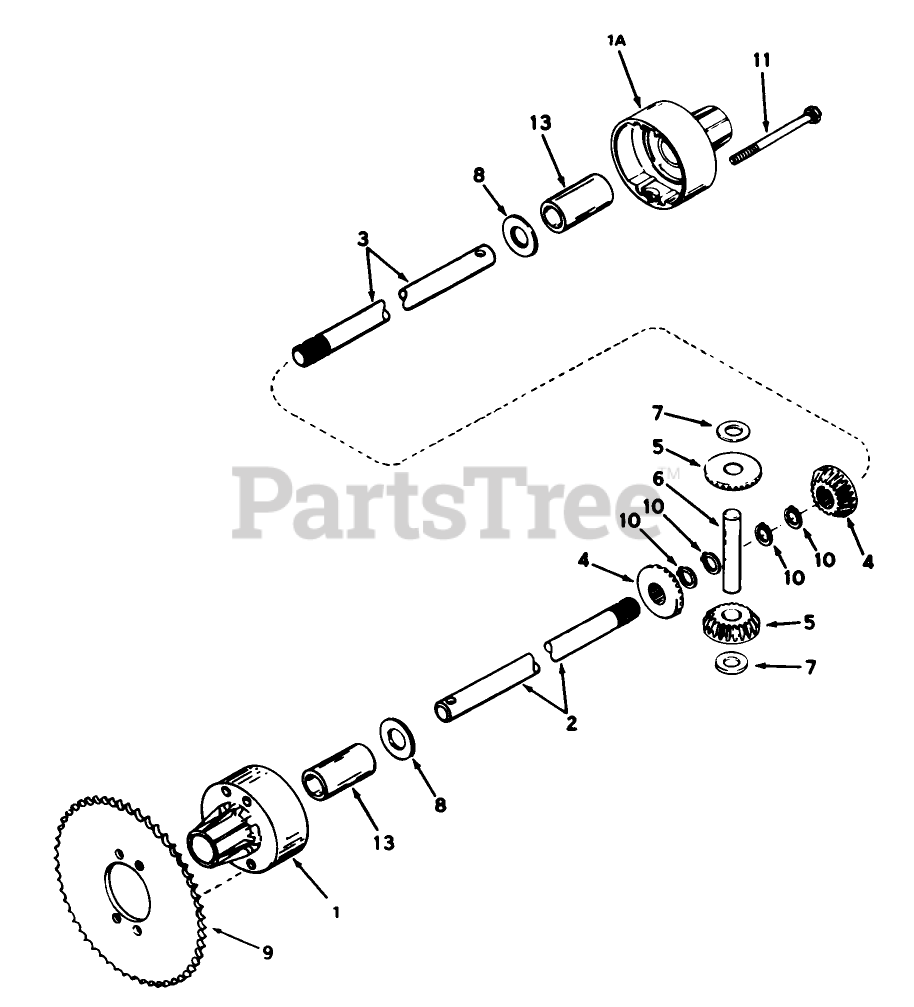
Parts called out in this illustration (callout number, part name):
1	Housing, Differential Carrier (Incl. Ref. #13)
1A	Housing, Differential Carrier (Incl. Ref. #13)
2	Axle (10-1/4" long)
3	Axle (18-7/8" long)
4	Gear Bevel
5	Gear Pinion
6	Pin Drive
7	Washer Thrust
8	Washer
9	Sprocket (See "Sprocket Chart" for optional sprocket)
10	Retaining Ring (pkg of 2)
11	Screw-Hex Hd.
13	Bushing
